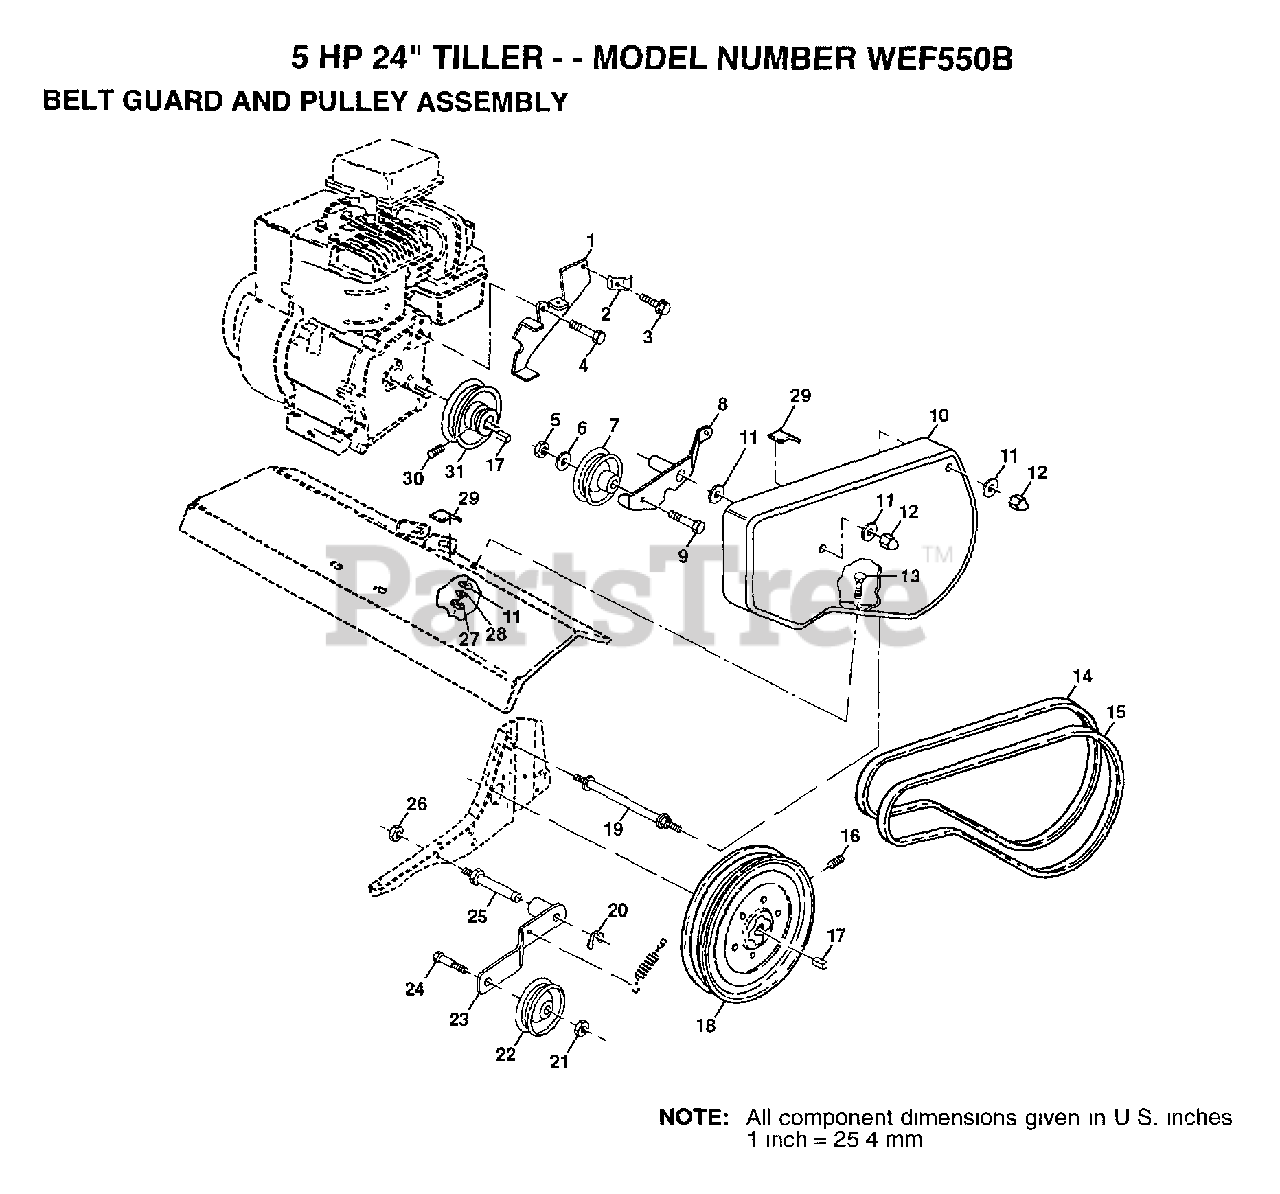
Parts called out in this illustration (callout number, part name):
2	CONDIUT CLIP T
5	NUT.HEX.3/8-16UNC
6	WASHER
7	PULLEY W/SPACER
8	ARM.ASM.REV.IDLER
11	WASHER
12	NUT-CAP TI
13	BOLT T
14	BELT-V
16	SET SCREW
17	KEY T
19	BOLT TI
20	KLIP RING TI
21	NUT
23	IDLER ARM TI
25	SHAFT IDLER TI
26	JAM NUT TI
28	LOCKWASHER
29	PAD IDLER TI
30	SET SCREW
31	ENGINE PULLEY TI
